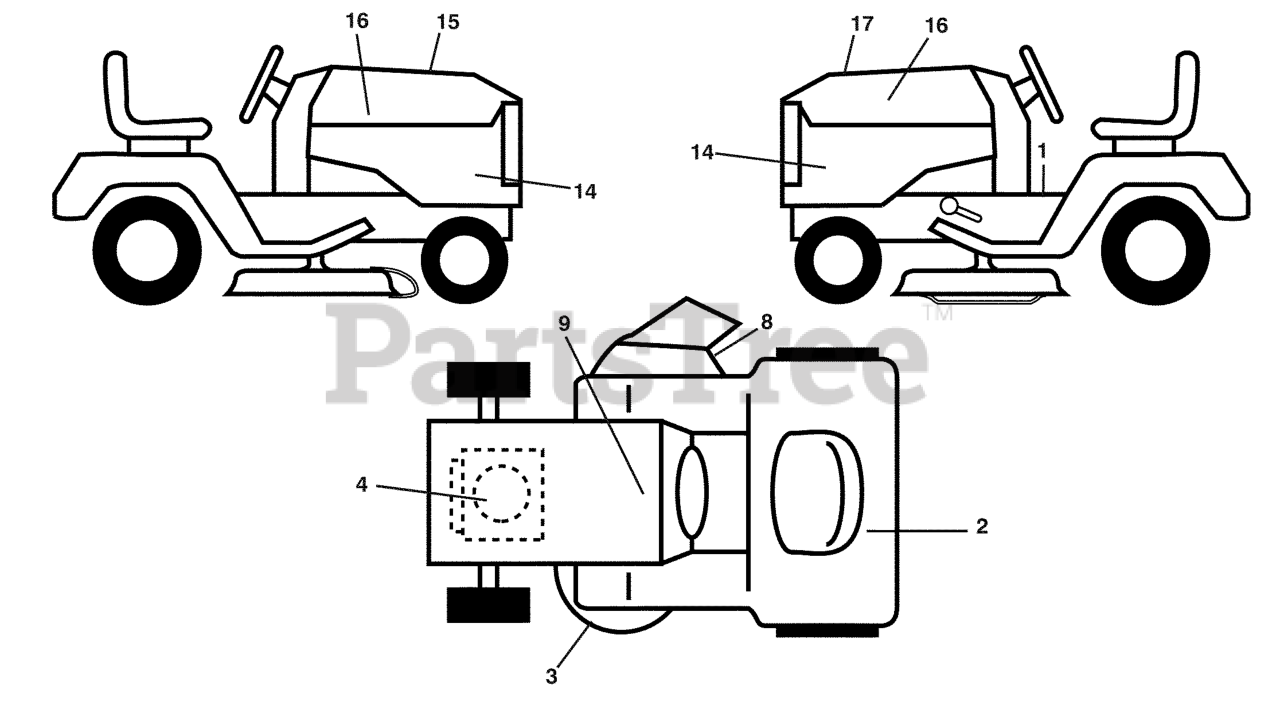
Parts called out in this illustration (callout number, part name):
1	DECAL.FENDER.WARNING.ENG
2	DECAL,ETHANOL E85 WARNING
3	DECAL.WARN.KEEP.HAND.AWAY
4	DECAL, ENGINE, HP
8	DECAL.MOWER.SCH.48/54
9	DECAL BTRY SYMBOLS
14	DECAL PANEL
15	DECAL.WARNING.CUST.RESP.E85.
16	DECAL.HOOD.LOGO.ORANGE.HUSQVAR
17	Decal, Replacement
